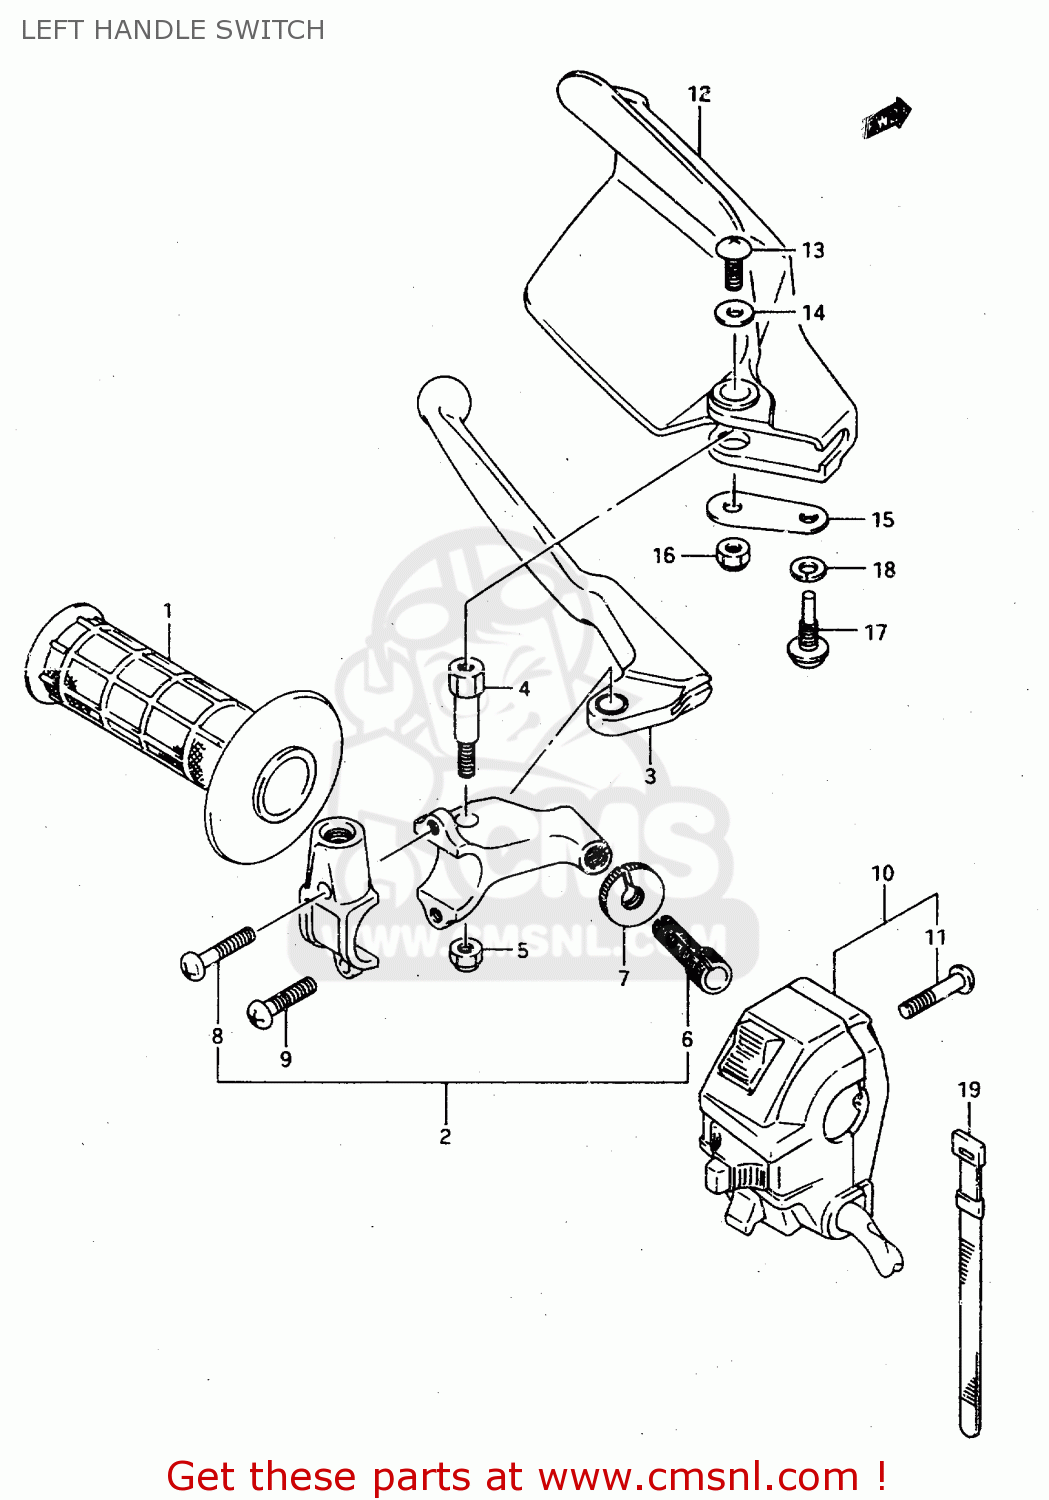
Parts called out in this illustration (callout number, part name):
1	GRIP,L
2	LEVER ASSY,CLUTCH
3	LEVER,CLUTCH
4	BOLT,LEVER SET
5	NUT 6MM
6	ADJUSTER,CABLE
7	NUT,LOCK
8	SCREW
9	SCREW(5X14)
10	SWITCH ASSY,HANDLE,L
11	SCREW
12	COVER,KNUCKLE,L
13	SCREW
14	WASHER (5.5X16X1.2)
15	PLATE,KNUCKLE COVER,L LWR
16	NUT 6MM
17	SCREW
18	WASHER,LOCK
19	CLAMP(L:120)
